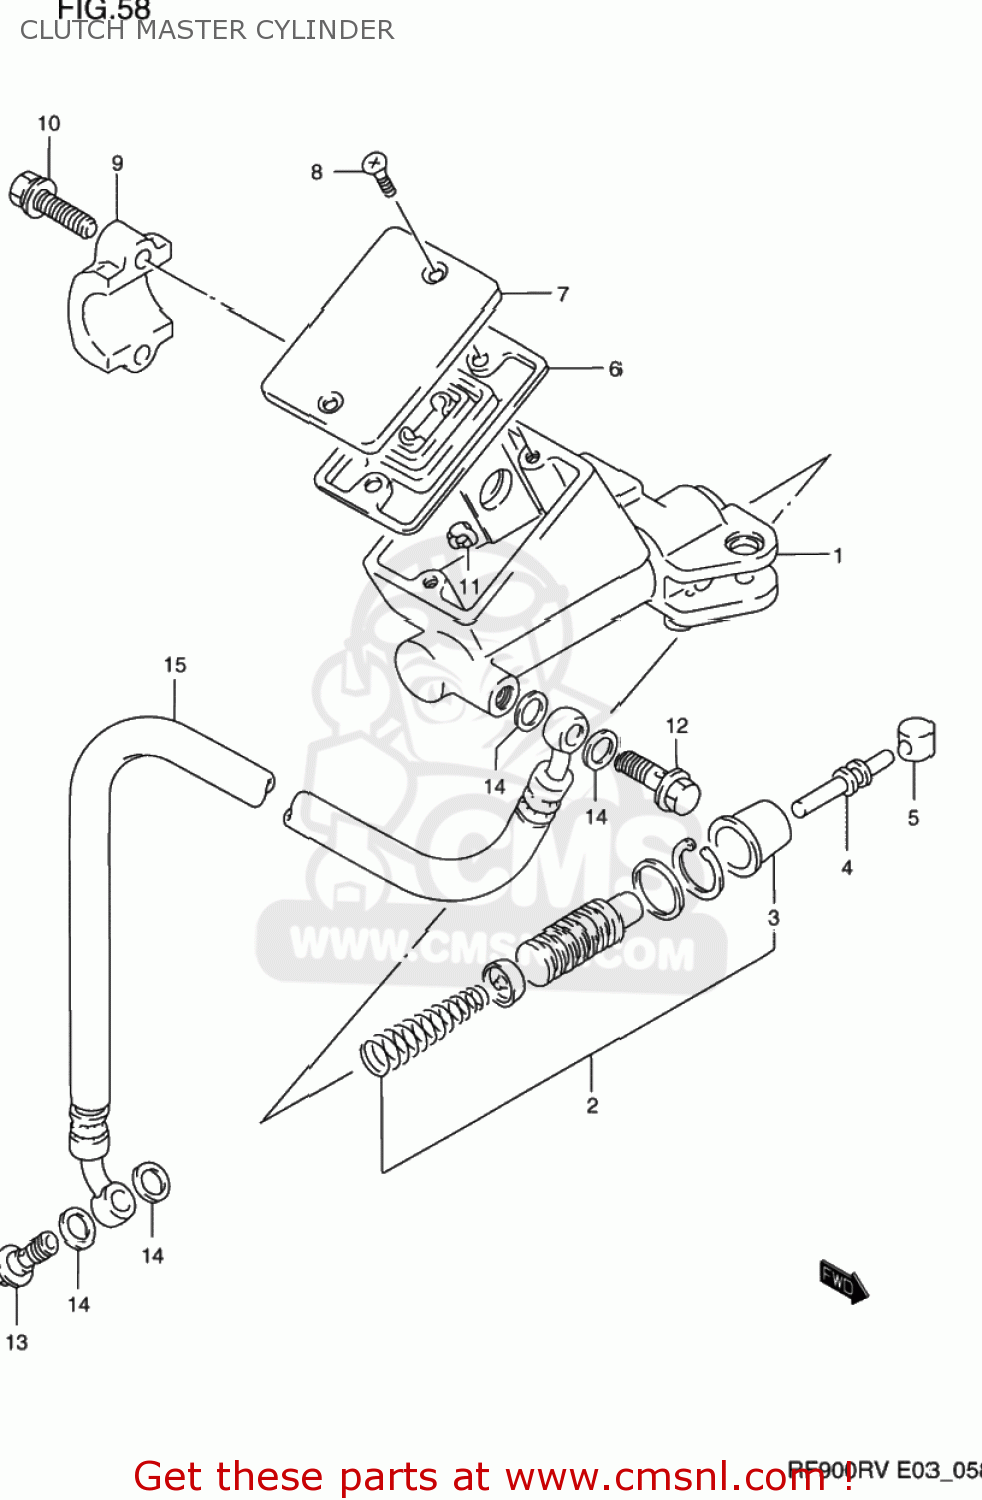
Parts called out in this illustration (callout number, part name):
1	CYLINDER ASSY,CLUTCH MASTER
2	PISTON & CUP SET
3	BOOT
4	ROD,PUSH
5	BUSH
6	DIAPHRAGM
7	CAP
8	SCREW
9	HOLDER
10	BOLT(6X25)
11	PROTECTOR
12	BOLT UNION
13	BOLT UNION
14	WASHER(10X15X1.5)
15	HOSE COMP,CLUTCH
